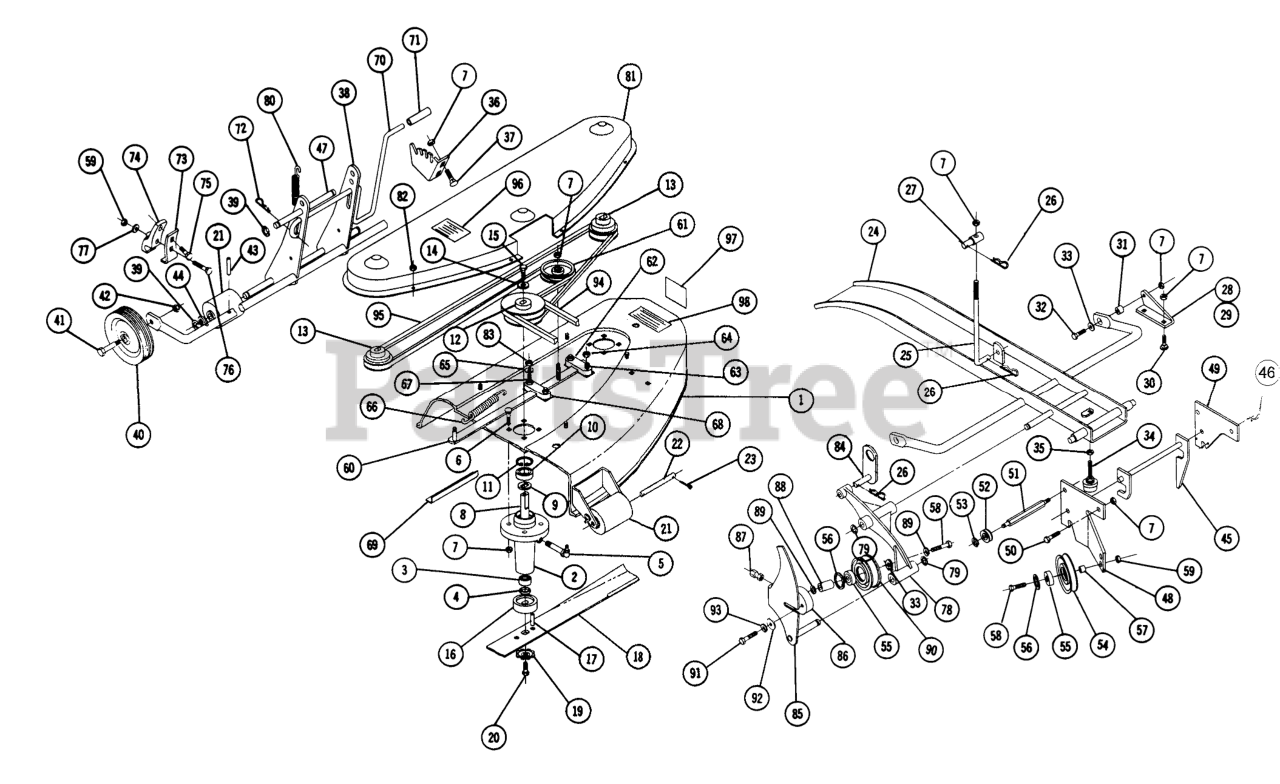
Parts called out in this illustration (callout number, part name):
1	Ass-y. Deck 42" Mower
2	Housing
3	NEEDLE BEARING
4	Seal
5	Fitting-Grease
6	Bolt 3/8-16 x 1
7	3/8-16 E.S.
8	Shaft Spindle
9	WASHER
10	Ball
11	INT SNAP RING
12	Center Pulley
13	End Pulley
14	WASHER
15	Bolt 3/8-16 x 7/8
16	SPINDLE CUP
17	SPIROL ROLL PIN
18	Blade 14"
19	WASHER
20	Bolt 3/8-16 x 7/8
21	Roller
22	Shaft
23	Cotter Pin
24	Washer
25	ROD LIFT
26	Hairpin
27	TRUNNION-LIFT
28	Bracket Deck R.H.
29	Bracket Deck L.H.
30	Bolt Carriage 3/8-16 x 3/4
31	SPACER
32	Bolt 3/8-16 x 1
33	Washer
34	Leveler
35	Nut, 5/16-18
36	Quadrant
37	Bolt-3/8-16 x 3/4
38	Ass-y. Gage Wheel Support
39	E Ring
40	Wheel
41	BOLT-SHOULDER
42	3/8-16 Jam Nut
43	Roll Pin
44	Washer
45	ASSY LATCH & SHAF R
46	Hairpin
47	Pin
48	MOUNTING BRACKET R
49	PLATE-MTG BRKT LH R (NS)
50	Bolt 3/8-16 x 1
51	SUPPORT MTG PLATE
52	ROLLER
53	Lock Rod
54	PULLEY IDLER
55	BEARING
56	INTERNAL SNAPRING
57	SPACER
58	Bolt, 3/8-16 x 1/2
60	ASSY BAR IDLER SUPPO
61	Idler Pulley
62	Side Block
63	Bolt-5/16-18 x 1/4
64	Nut 5/16-18
65	Washer
66	SPRING R
67	Bolt-5/16-18 x 1 1/2
68	SLIDE
69	ANGLE
70	Rod Height Control
71	Grip Handle
72	Hairpin
73	Clip-Axle
74	SUPPORT AXLE
75	Bolt-Carriage
76	Bolt Carriage 3/8-16 x 1
77	Washer
78	ARM PIVOT R
79	RING LAM L 262
80	Spring
81	Cover
82	HEX NUT 10-32 E.S.
83	Nut-Nylok
84	Cam Arm
85	ASSEMBLY CAM LEVE R
86	Ass-y Idle Support
87	Nut
88	SPACER
89	Lockwasher-3/8 Int.Tooth
90	PULLEY IDLER
91	Bolt 3/8-16 x 7/8
92	WASHER
93	Lockwasher
94	Screw
95	V BELT
96	Decal Belt Installation
97	Decal
98	Decal
